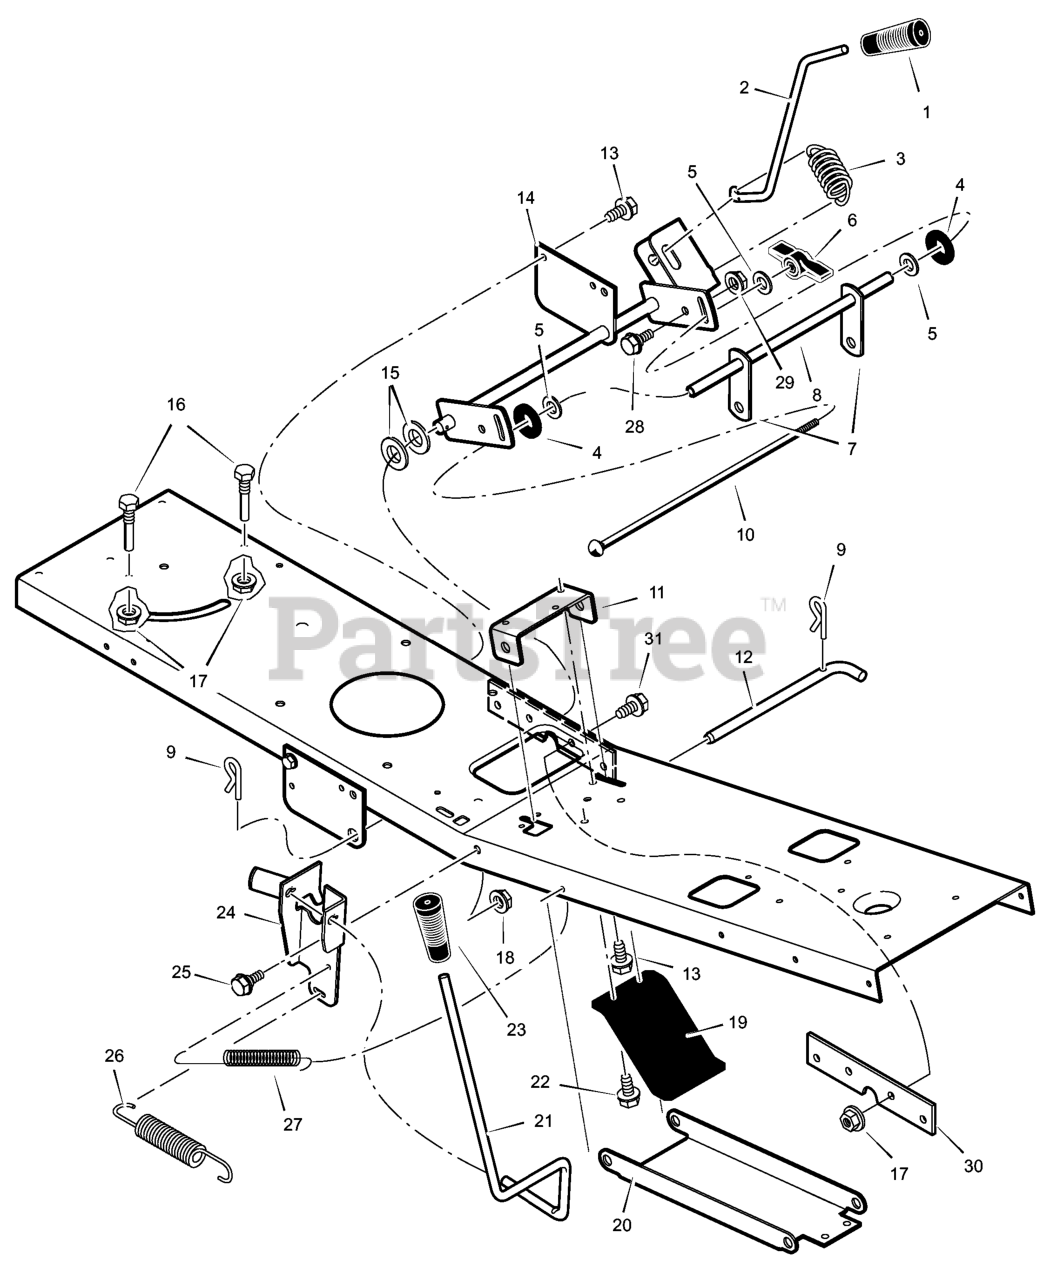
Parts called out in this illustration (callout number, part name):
1	Grip, Lift Lever
2	Lever, Lift
3	Spring, Extension
4	Pad, Friction
6	Wingnut
7	Link, Lift
8	Tube, Spacer
9	Pin, Hair
10	Bolt, Carriage
11	Bracket, Front Hanger Pivot
12	Pin, Front Hanger
14	Arm Assembly, Lifter
15	Washer
16	Screw, Guide
17	Nut, Flange
18	Nut, Flange
19	Spring, Leaf
20	Hanger, Front
21	Lever, PTO
23	Grip, PTO
24	Bracket, PTO
25	Bolt, Shoulder
26	Spring, Extension
27	Spring, Extension
28	Bolt, Shoulder
29	Nut
30	Plate, Reinforcement
